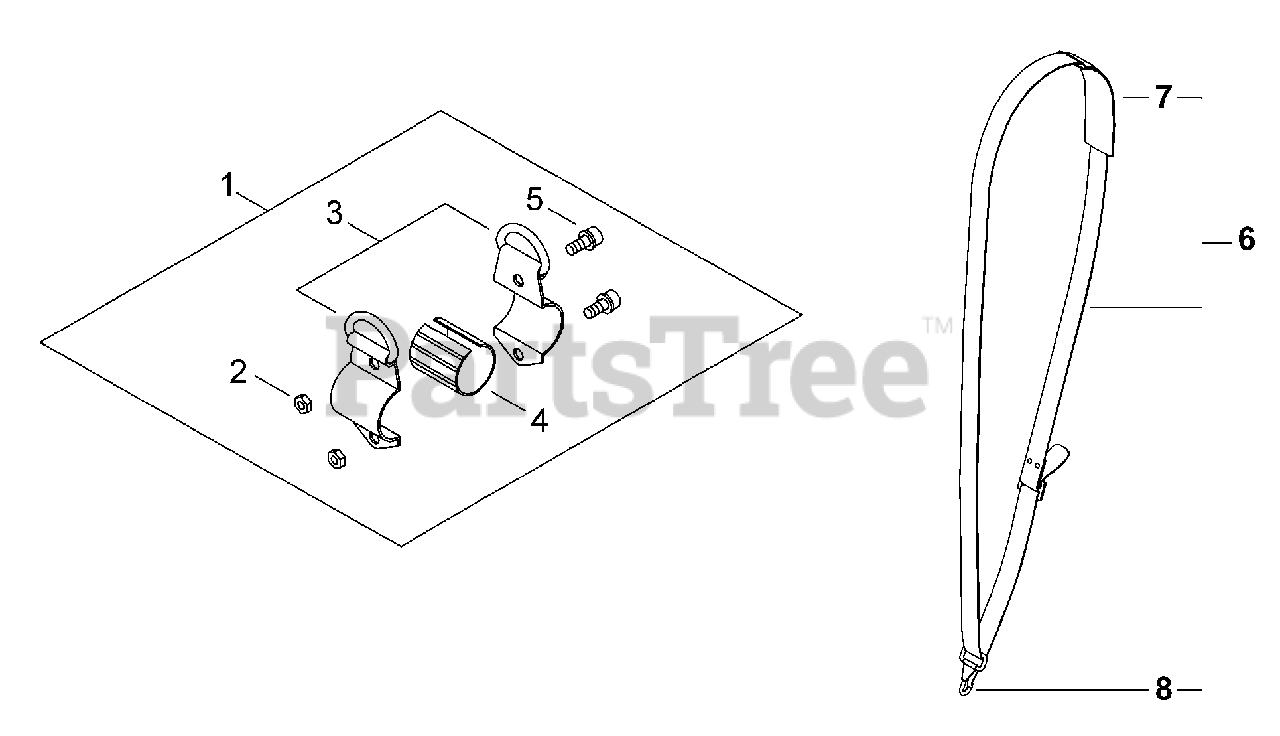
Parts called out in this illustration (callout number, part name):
1	HANGER ASSY
2	NUT M5
3	HANGER SET
4	SPACER
5	BOLT M5×12
6	HARNESS ASSY
7	PAD, SHOULDER
8	HOOK, SNAP
